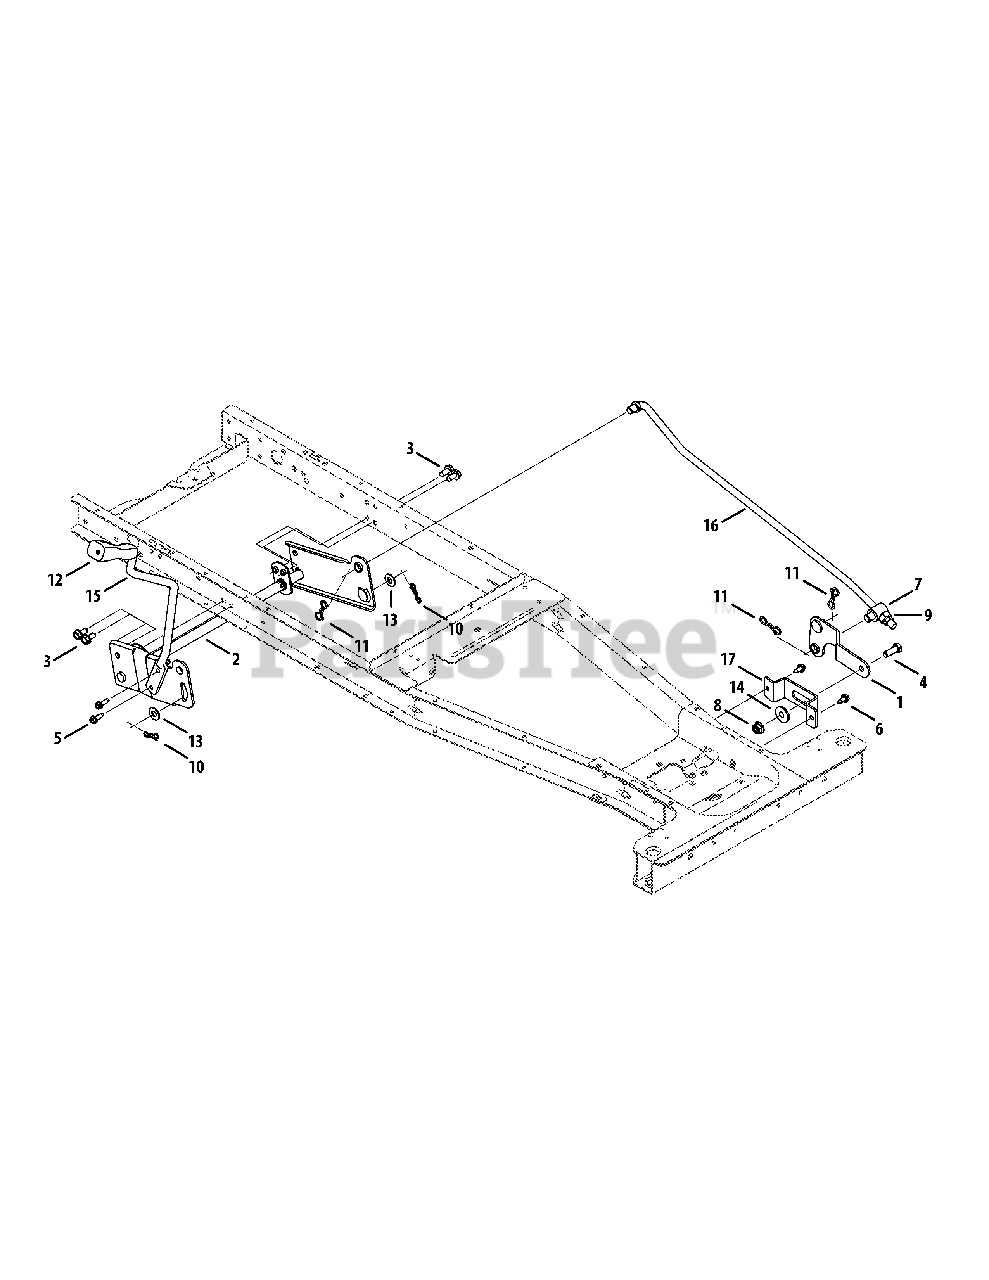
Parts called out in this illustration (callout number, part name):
1	Front Hanger Bracket Assembly
2	Lift Assembly Shaft
3	Tap Screw, 5/16-18, .750
4	Hex Head Screw, 3/8-16, 1.00
5	Tap Screw, 1/4-20, 0.750
6	Tap Screw, 1/4-20 X .625
7	Ferrule, .50 X .50
8	Flange Lock Nut, 3/8-16
9	Flange Lock Nut, 1/2-13
10	Bow-Tie Cotter Pin, 72
11	Bow-Tie Cotter Pin, 91
12	Grip Handle, 1/2
13	Flat Washer, .406 X .875 X .059
14	Shoulder Spacer, .625 ID X .169
15	Deck Lift Rod
16	Lift Link Rod
17	Front Deck Mounting Bracket
